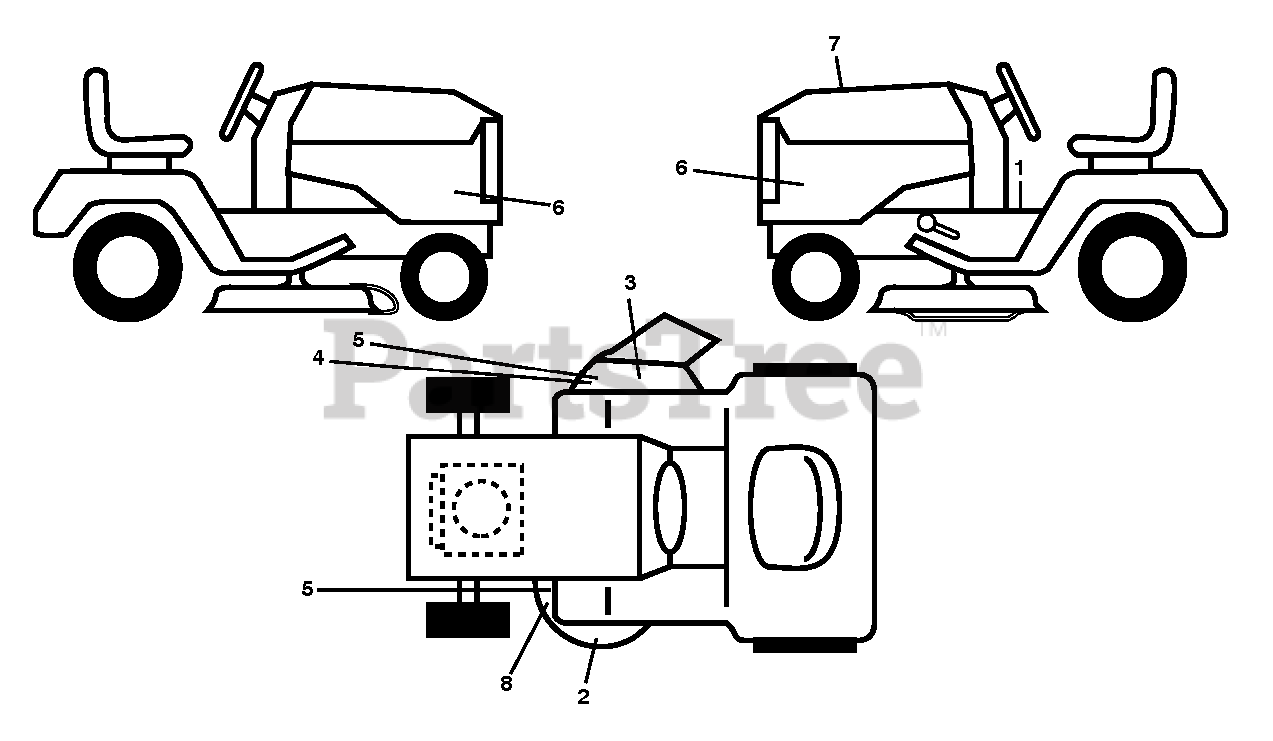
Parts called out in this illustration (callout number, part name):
1	DECAL.WARNING.2007.ENG/FR
2	DECAL.54DECK.CLEARCUT.VER2.18
3	DECAL.TRACT/ZTR.DECKWARN.HUSQ
4	DECAL BELT ROUTING DECAL DECAL
5	DECAL.DECK.CLEARCUT.NOSTEP
8	DECAL DECK DECAL DECAL.POP.LIF
